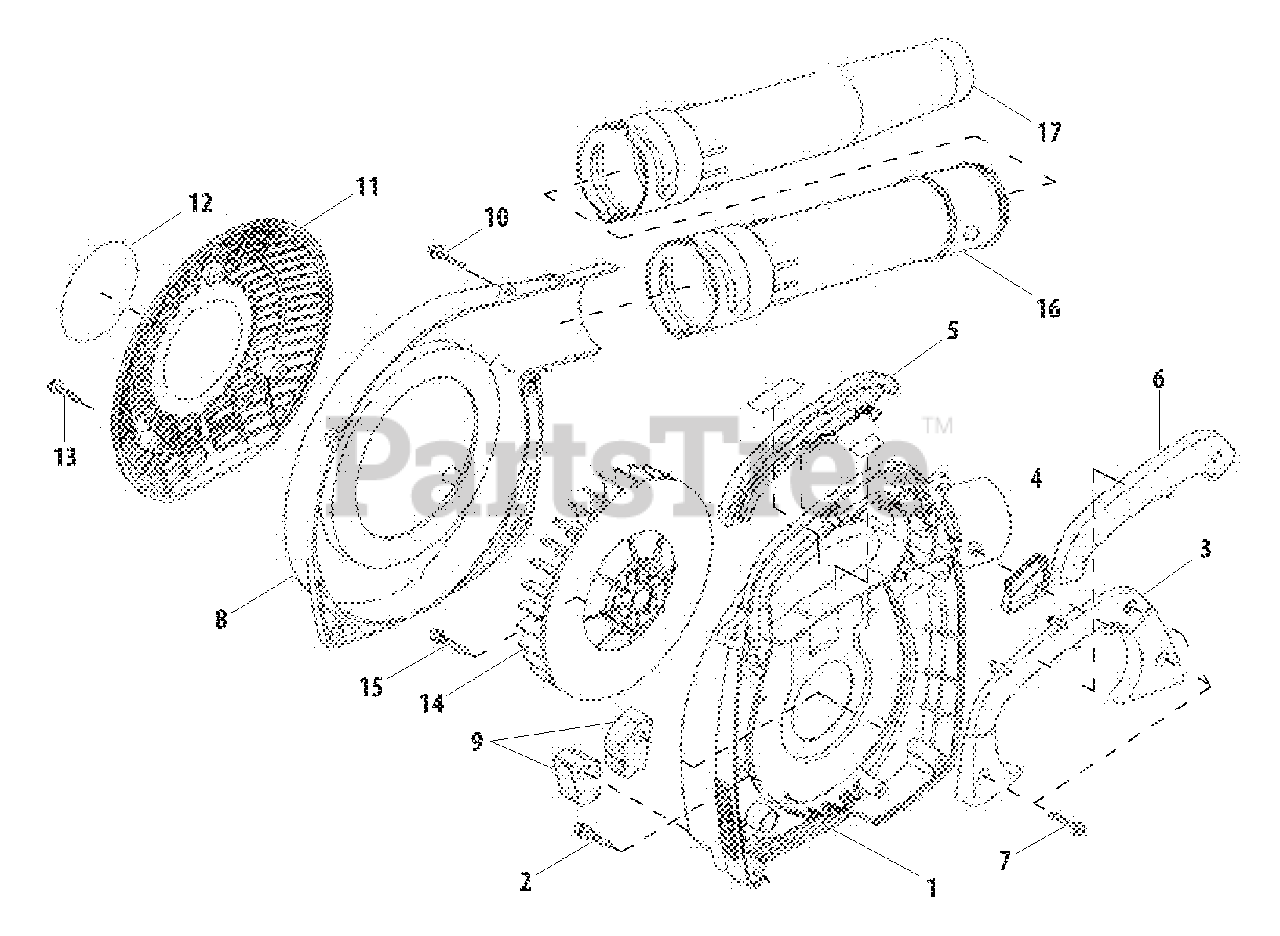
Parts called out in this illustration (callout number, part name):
1	COVER, FAN - RIGHT
2	SCREW - 5X16
3	HANDLE
4	TRIGGER, THROTTLE
5	GRIP
6	GRIP
7	SCREW
8	COVER, FAN - LEFT
9	CUSHION - REAR
10	SCREW
11	COVER, INTAKE
12	LABEL - TRADE
13	SCREW
14	FAN
15	SCREW - 5X20
16	PIPE
17	NOZZLE
